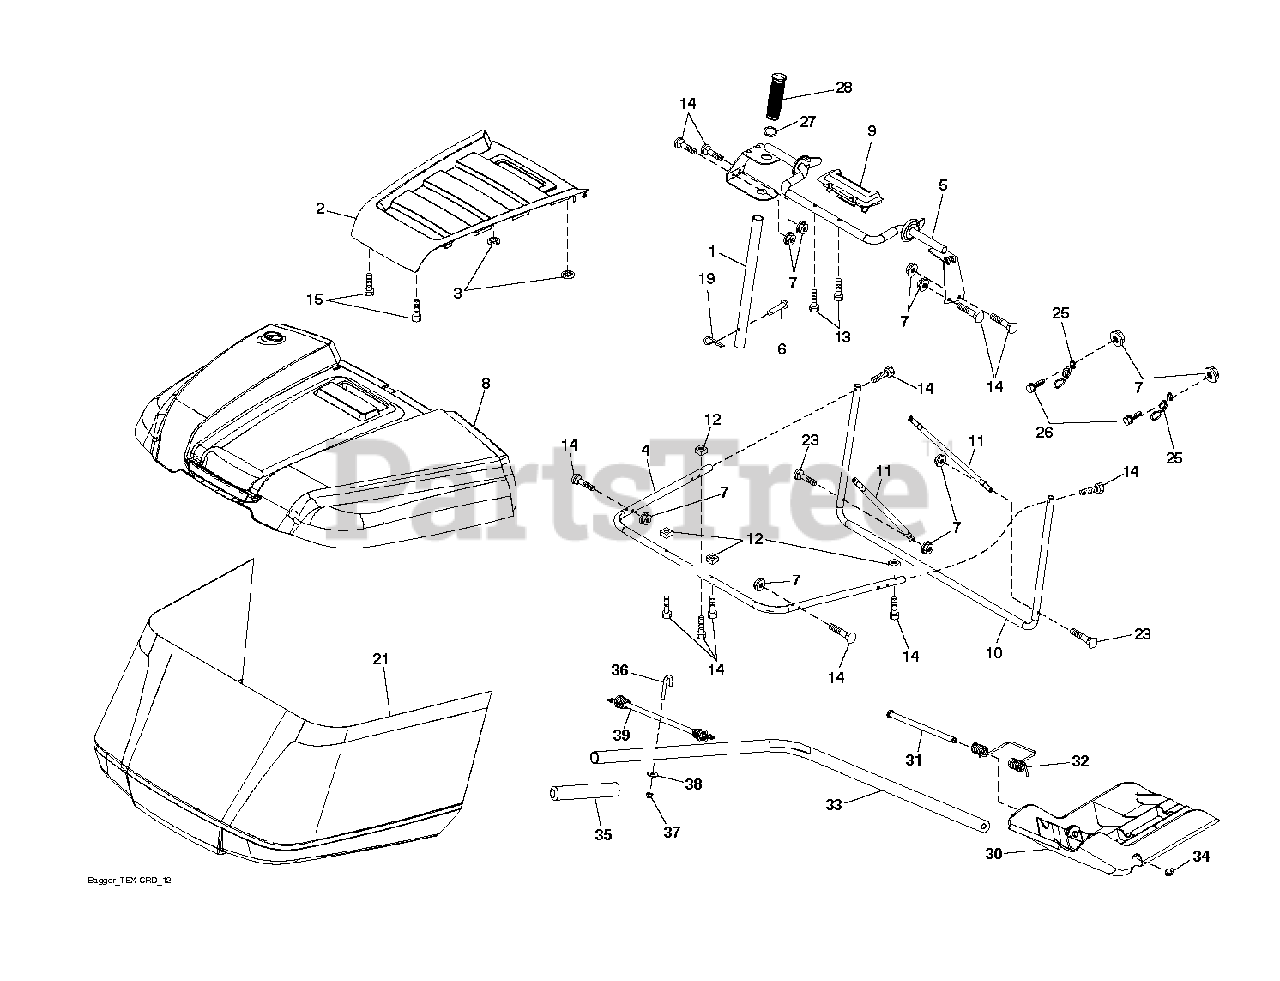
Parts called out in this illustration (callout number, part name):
1	TUBE.HANDLE.BAGGER.CRD/SRD.BLA
2	APPLIQUE.TOP.BAG.SRD.ORANGE
3	NUT.PUSH.156
4	SUBASM.TOP.TUBE.TEX.CRD
5	FRAME.ASM.TOP.BAGGER.SRD
6	RIVET,DRILLED
7	NUT T
8	BAGGER.TOP.SRD.APPLIQUE
9	INSERT.HANDLE.BAGGER.(2 2)
10	FRAME FRAME.FRONT.TEX.CRD
11	BRACE BRACE SIDE TUBE
12	NUT.SQUARE.1/4
13	SCREW.1/4X1.150.HXWSH
14	BOLT.SHOULDER.HX.WSH.1/4X1.150
15	SCREW,#8.FLAT.HEAD.DRILL.TIP
19	PIN.COTTER.5/16.BOW TI
21	BAG SUBASM. TEX CRD GEN 2 HUSQ
25	SPRING.LATCH.BAGGER.SRD
26	SCREW HEX CRT
27	RB GROMMET.RUBBER.SRD
28	GRIP.HANDLE.BLACK
30	PLUG PLUG
31	PIN PIN.HINGE
32	SPRING SPRING DOUBLE TORSION
33	SHAFT SHAFT TEX CRD MULCH PLU
34	E-RING.5/16"
35	GRIP GRIP MULCH PLUG HAND
36	BOLT BOLT J
39	BUBGEE BUBGEE TEX CRD
